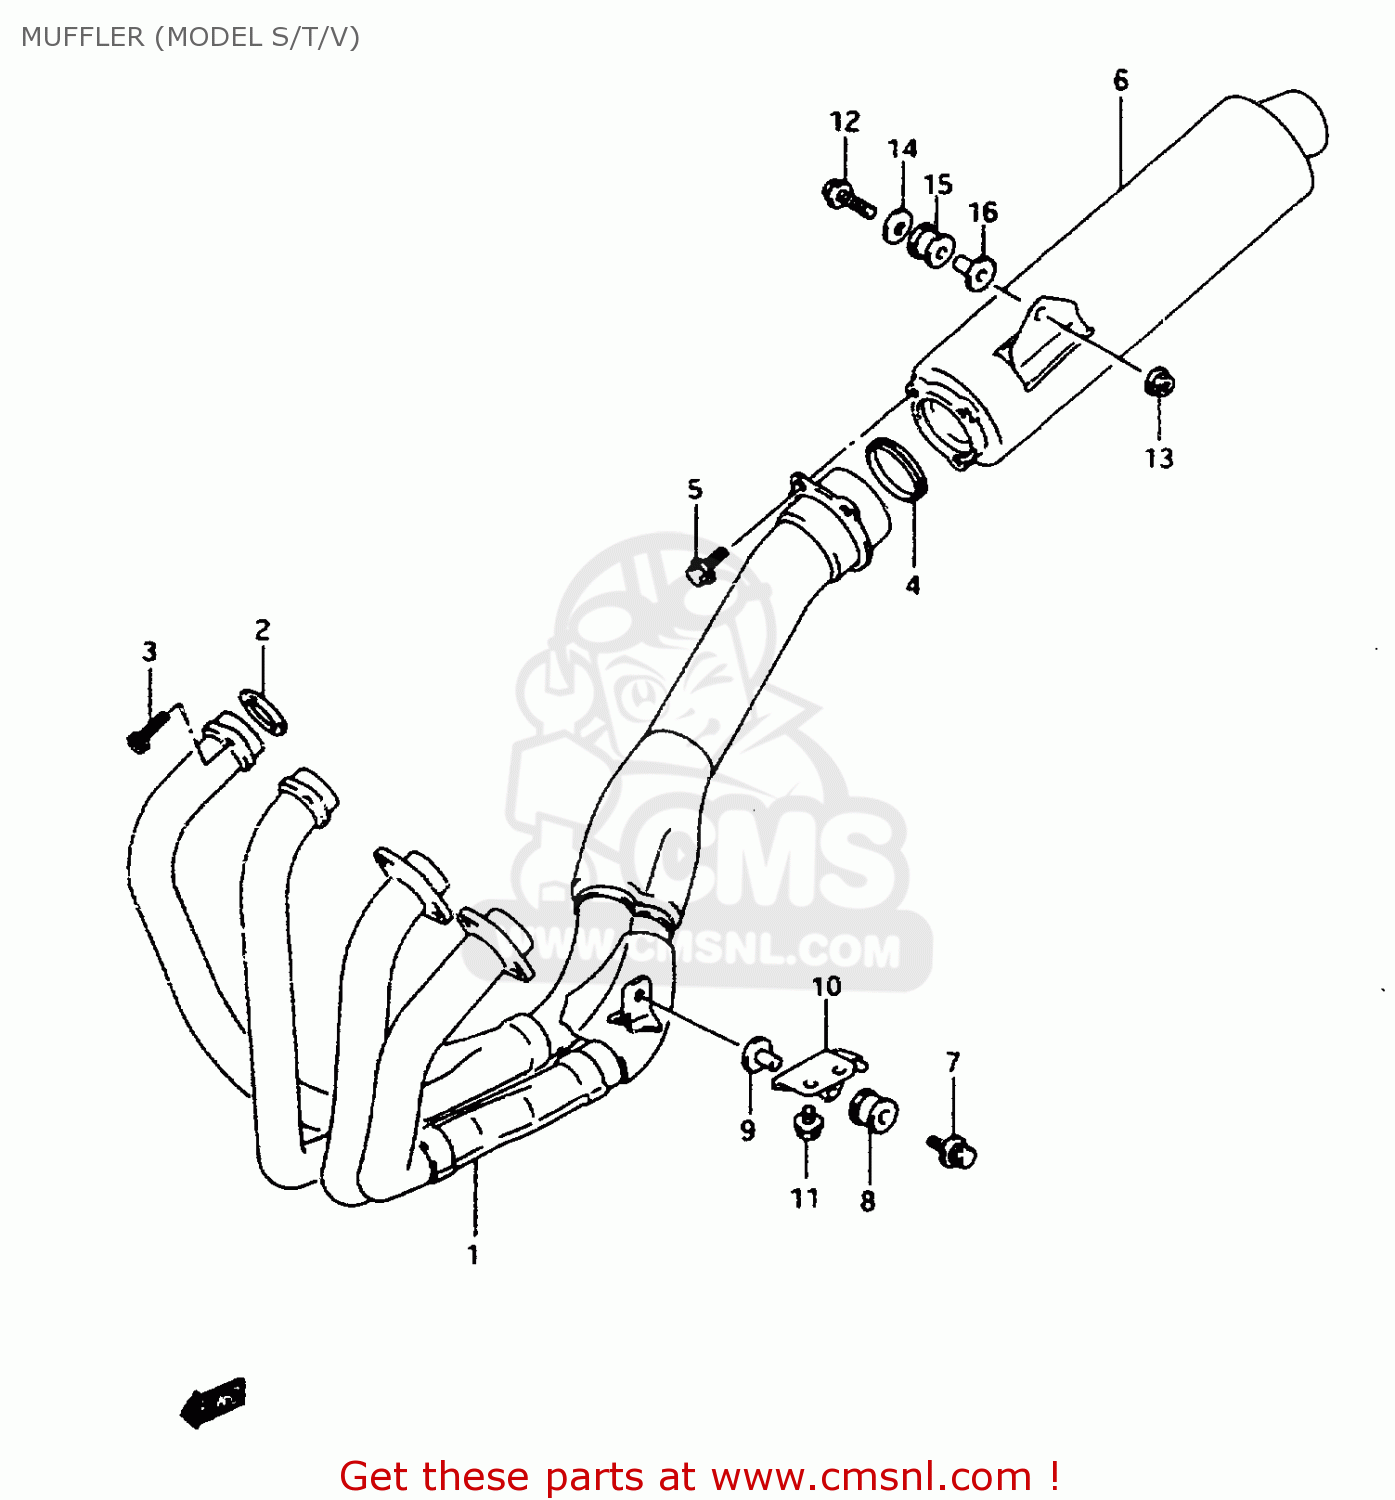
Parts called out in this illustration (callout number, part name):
1	EXHAUST
2	GASKET,EXHAUST PIPE
3	BOLT
4	GASKET,MUFFLER JOINT
5	BOLT(8X20)
6	BODY,MUFFLER
7	BOLT 8X45
8	CUSHION
9	SPACER(8.6X12X24.2)
10	BRACKET,MUFFLER SUPPORT FR
11	BOLT
12	BOLT
13	NUT
14	BOLT
15	NUT
16	SPACER(8.6X12X27.1)
17	CUSHION
18	SPACER(8.6X12X27.1)
